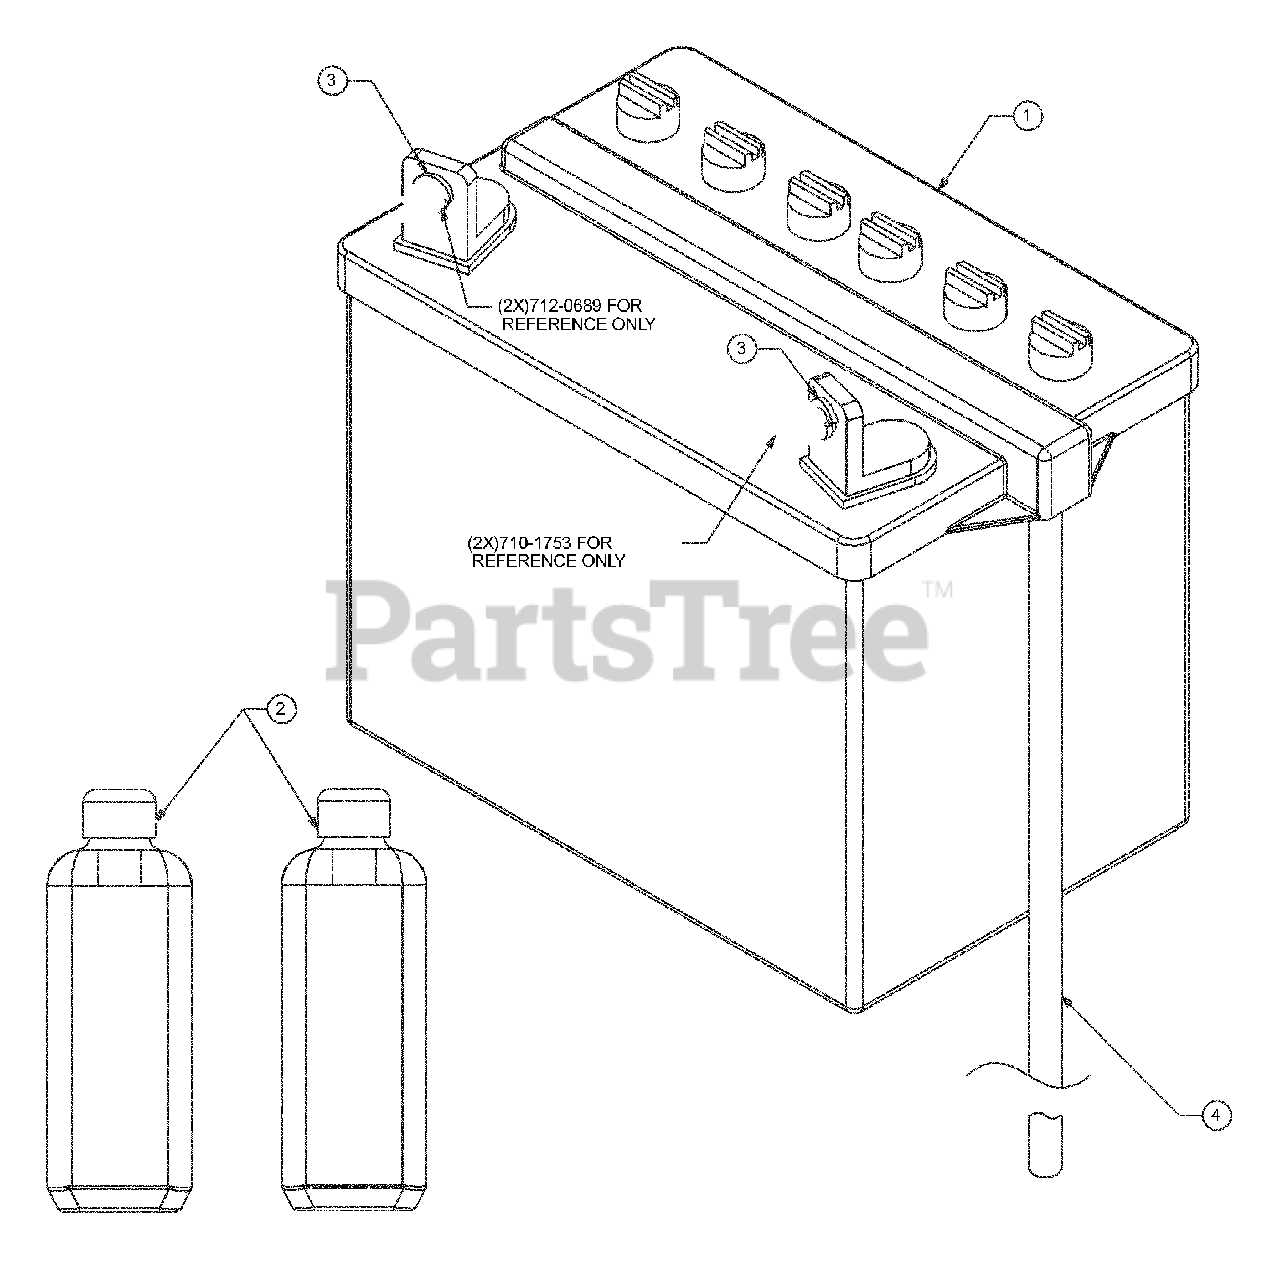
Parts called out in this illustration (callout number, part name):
1	BAT:U1:245 CCA DRY VENTED TOP
2	PACK:ACID: 1 LITER
3	WASH:LOCK:B6 DIN 127
